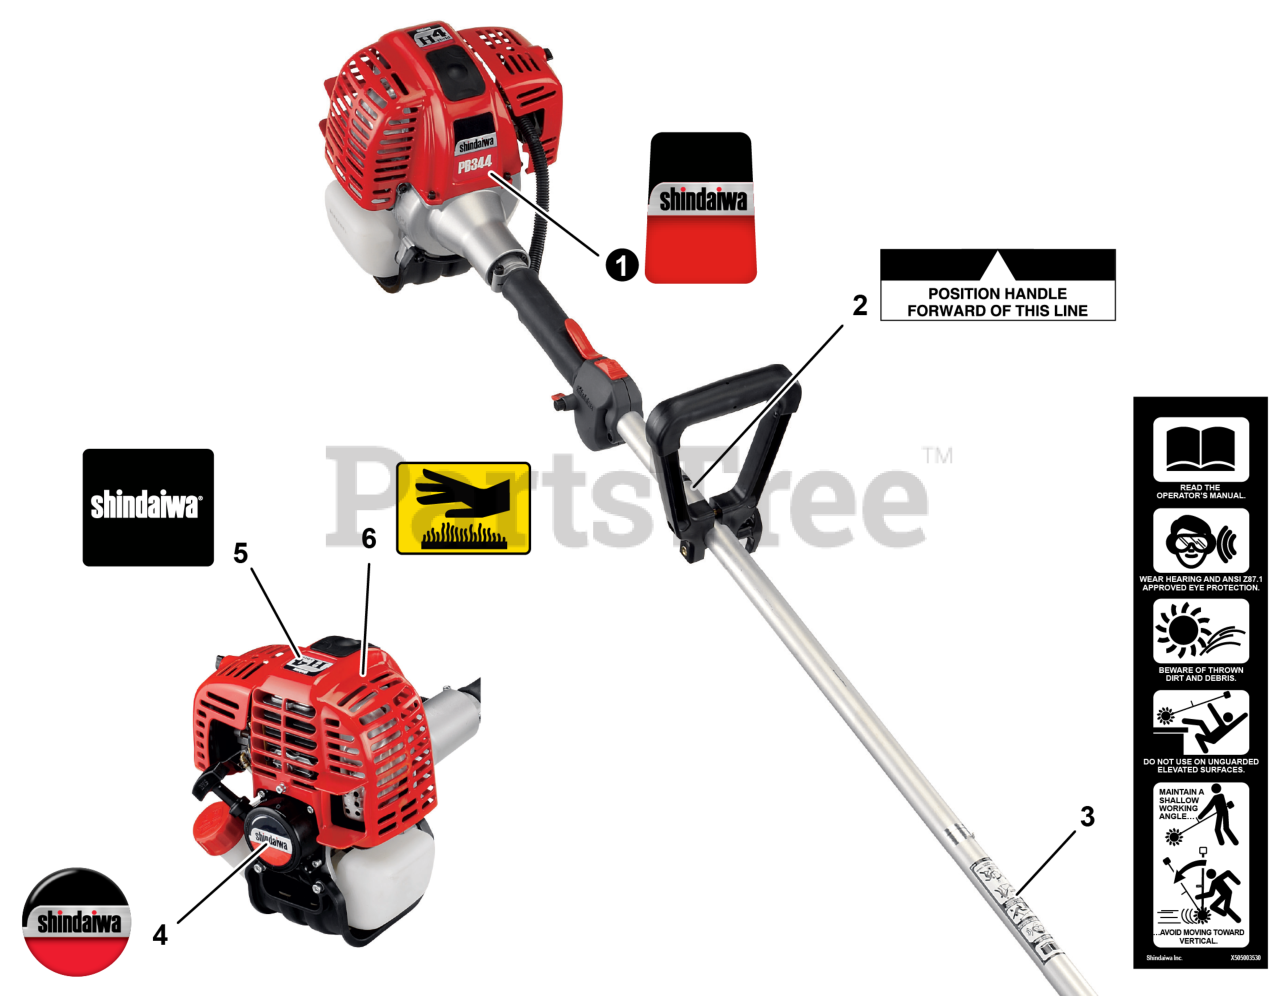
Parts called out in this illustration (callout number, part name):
1	LABEL - MODEL PS344
2	LABEL - HANDLE
3	LABEL - CAUTION
4	LABEL - RECOIL STARTER
5	LABEL - SHINDAIWA
6	LABEL - CAUTION - HOT
